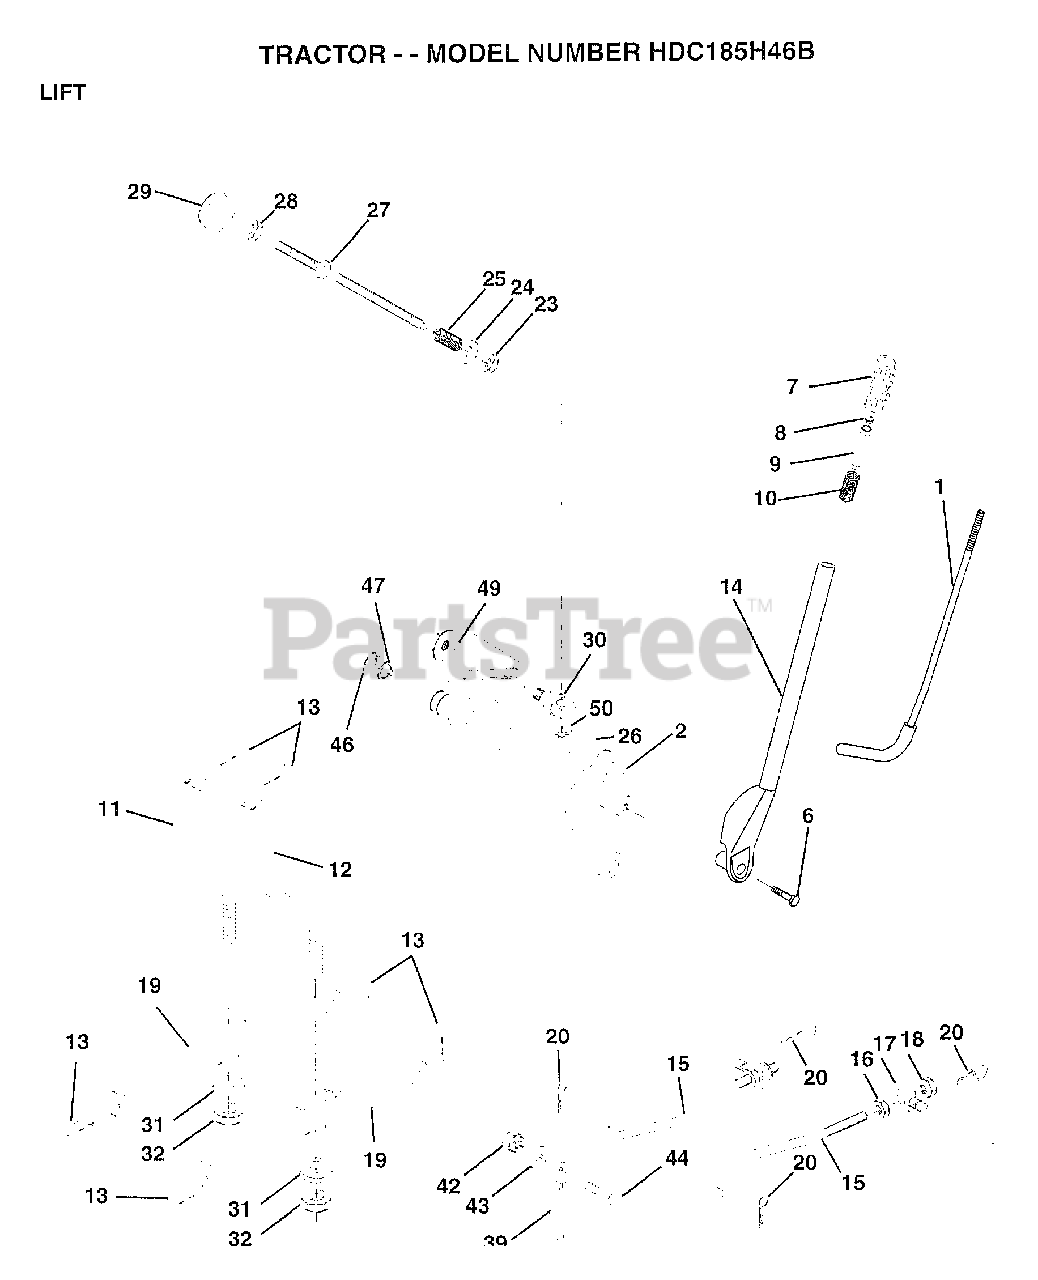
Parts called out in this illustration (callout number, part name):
1	LEVER ROD LT
2	SHAFT LIFT W/IND
6	"BOLT,HEX"
7	GRIP
10	SPRING T
11	LINK.LIFT.LH.GTV
12	LINK.LIFT.RH.GTV.
15	LINK.FRONT
16	NUT
17	TRUNION
18	NUT.LK.W/WSH.1/2.
19	ARM SUSP REAR
20	RETAINER.SPRING
23	NUT T
24	WASHER
25	SPRING T
26	PIN, COTTER 3/32 X 1/2
28	NUT
29	KNOB INF 3/8-16
30	TRUNNION
31	BEARING PVT LH
32	NUT.CROWNLOCK.3/8
39	STOP.OVER.CENTER
43	WASHER GT
44	BOLT
46	E-RING
47	WASHER
49	NUT.HXFLG.LOCK.
50	NUT PUSH M
